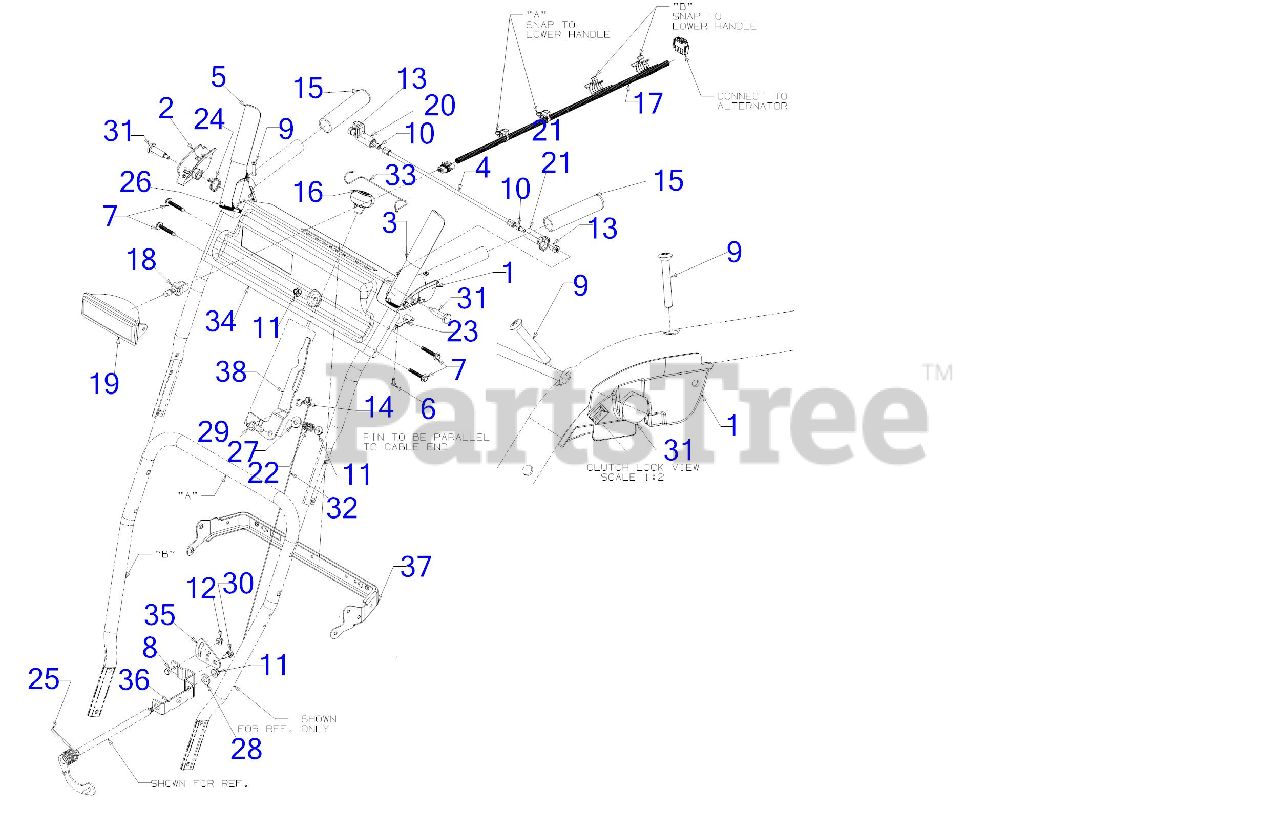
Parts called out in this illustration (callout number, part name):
1	CLUTCH LOCK HANDLE ASSEMBLY (LH)
2	CLUTCH LOCK HANDLE ASSEMBLY (RH)
3	HANDLE ASSEMBLY (LH)
4	PIVOT ROD
5	HANDLE ASSEMBLY (RH)
6	SCREW #8-16 x .50
7	SCREW 1/4-20 x 1.625
8	SCREW 1/4-20 x .620 GR5
9	SCREW #10-24 x 1.375
10	SCREW 1/4-20 x .50
11	FLANGE LOCK NUT 5/16-18
12	FLANGE LOCK NUT
13	HEX NUT W/PATCH
14	INTERNAL COTTER PIN
15	GRIP-1.0 ID x 5.0 LG
16	SHIFT KNOB
17	HALOGEN HEADLGHT HARNESS
18	HALOGEN BULB
19	LAMP HOUSING
20	LOCK PLATE
21	CLUTCH LOCK CAM
22	COMPRESSION SPRING
23	CLUTCH SPRING
24	TORSION SPRING
25	TORSION SPRING
26	RUBBER BUMPER
27	FLAT WASHER .385X.870X.090
28	FLAT WASHER
29	SHOULDER BOLT
30	SHOULDER SCREW
31	SHOULDER SCREW .437 x 1.345 1/4-20
32	SPEED SELECTOR CABLE (STEEL)
33	RETAINER
35	PIVOT BRACKET
36	SHIFT SPEED BRACKET
